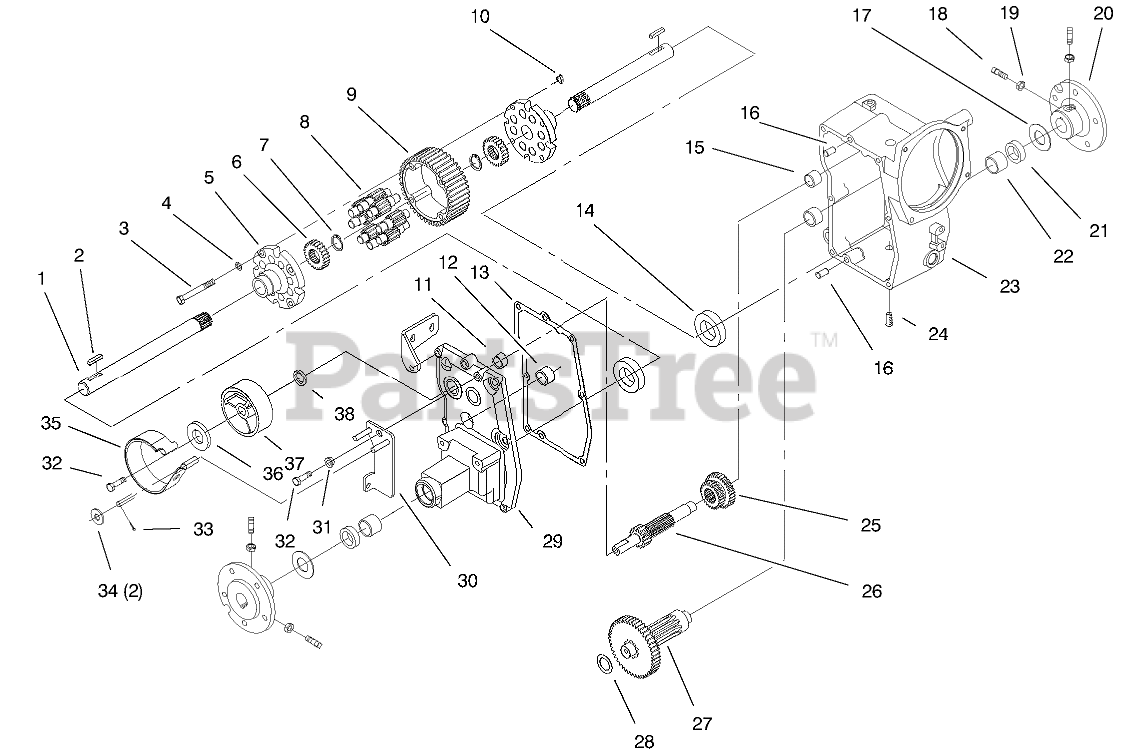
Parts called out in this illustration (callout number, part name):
1	AXLE-REAR
3	BOLT-HEX
4	WASHER
5	END CAP-DIFFERENTIAL
6	GEAR-AXLE DIFFERENTIAL
7	RING-SNAP
8	GEAR-PINION, 11T
9	GEAR-DIFFERENTIAL RING, 43T
11	BEARING-NEEDLE
12	BEARING-NEEDLE
13	GASKET-CASE
14	BEARING-BALL
15	BEARING-NEEDLE
16	PIN-LOCATING
17	WASHER-THRUST
18	SCREW-SET, SQH
19	NUT-JAM
20	HUB-WHEEL
21	SEAL-OIL
22	BEARING
23	CASE-LH
24	PLUG-PIPE
25	GEAR-SLIDING
26	SHAFT-BRAKE
27	GEAR ASM
28	WASHER-THRUST
29	CASE-RH
30	Arm-PIVOT, Brake
31	CAM-SPACER
32	SCREW-HH, LOCK
33	PIN-COTTER
34	WASHER-FLAT
35	BAND-BRAKE
36	WASHER
37	DRUM-BRAKE
38	SEAL-OIL
